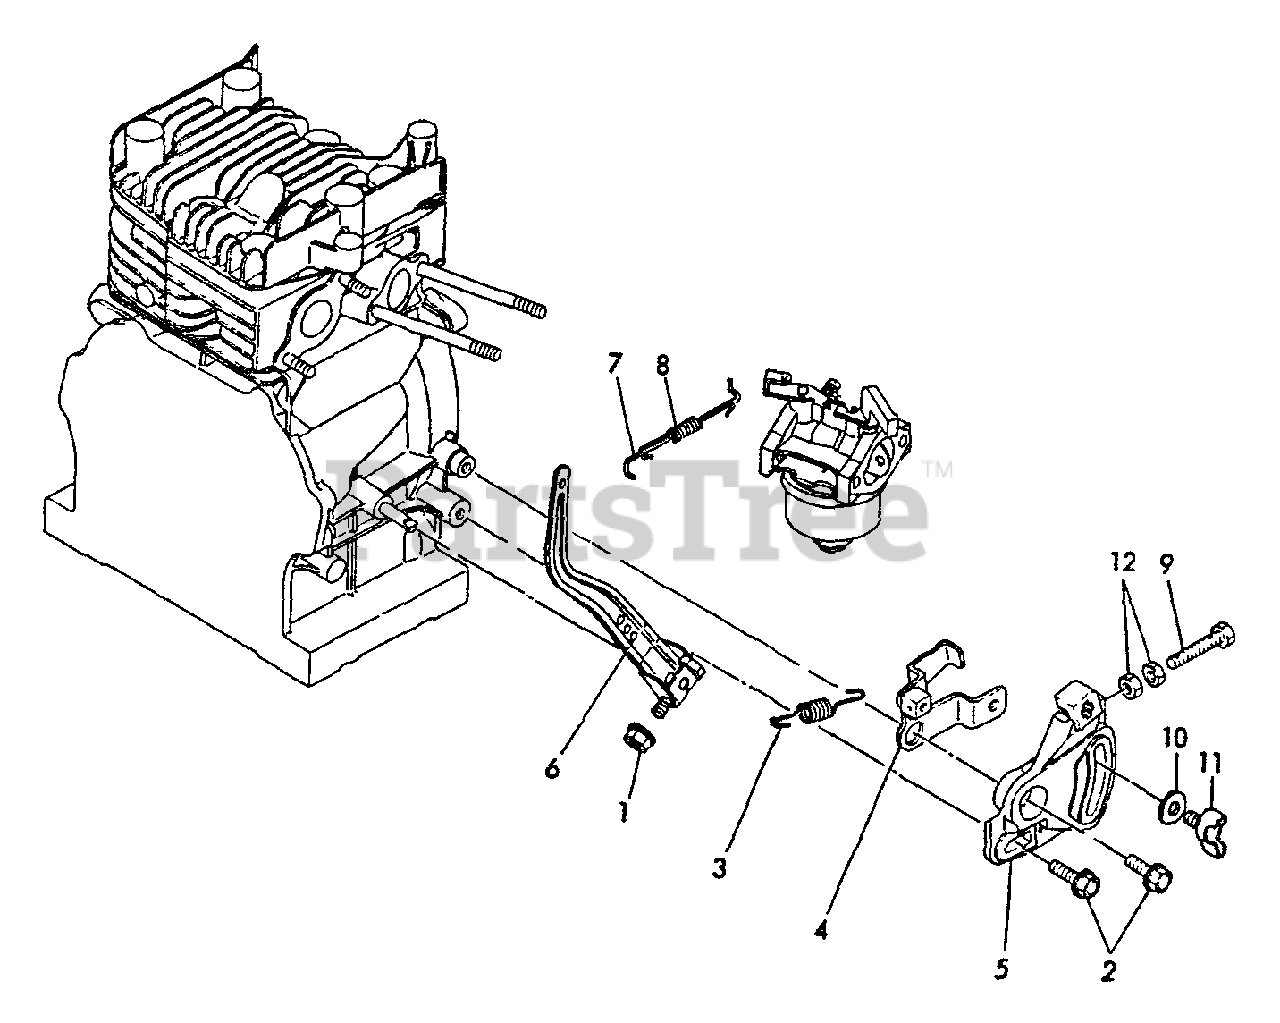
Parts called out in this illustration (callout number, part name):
1	U-NUT M6
2	BOLT - 6×20
3	SPRING, REGULATOR
4	HANDLE ASSY, REGULATOR
5	BRACKET, REGULATOR
6	LEVER, GOVERNOR
7	LINK, THROTTLE
8	SPRING, TENSION
9	BOLT
10	WASHER - 6
11	THUMBSCREW - 6×15
12	LOCKNUT - 6 -- PLATED
